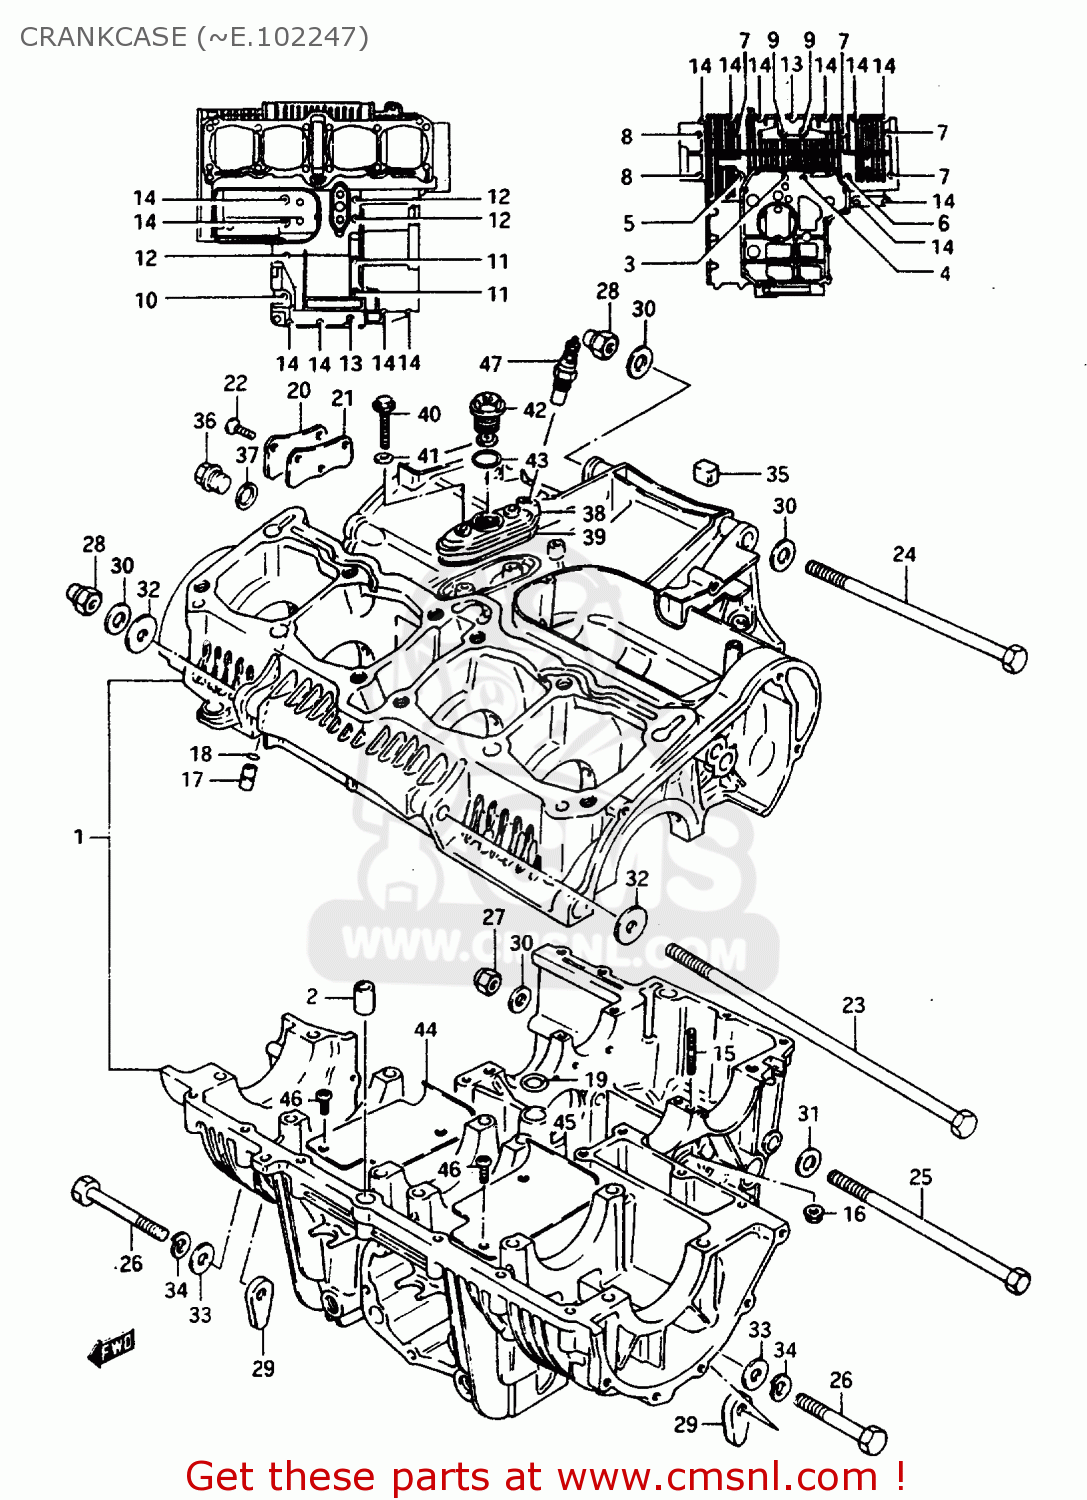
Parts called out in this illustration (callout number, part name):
1	CRANKCASE SET
2	PIN
3	BOLT
4	BOLT(8X135)
5	BOLT(8X115)
6	BOLT(8X100)
7	BOLT (8X90)
8	BOLT (8X65)
9	BOLT 8X60
10	BOLT, UPPER
11	BOLT
12	BOLT (6X75)
13	BOLT 6X55
14	BOLT
15	STUD 6X50
16	NUT
17	UNION
18	O RING(D:1.05,ID:3.1)
19	O RING(D:3.2,ID:12.9)
20	CAP,OIL GALLERY
21	GASKET,OIL GALLERY (MCA)
22	SCREW
23	BOLT
24	BOLT 10X180
25	BOLT(10X165)
26	BOLT 10X60
27	NUT (10MM)
28	NUT
29	NUT
30	WASHER
31	WASHER
32	WASHER
33	WASHER (10.5X20X3.2)
34	LOCK WASHER
35	PAD,CYLINDER
36	PLUG (14X12)
37	GASKET(14X19.2X2) (NAS)
38	HOUSING,OIL PRESSURE SWITCH
39	O RING,PRESSURE SWITCH HOUSING
40	BOLT
41	WASHER
42	SWITCH ASSEMBLY
43	O RING(D:1.9,ID:18.8)
44	PLATE,OIL SEPARATOR
45	PLATE,OIL SEPARATOR
46	SCREW
47	GAUGE ASSEMBLY,OIL TEMPERATURE
